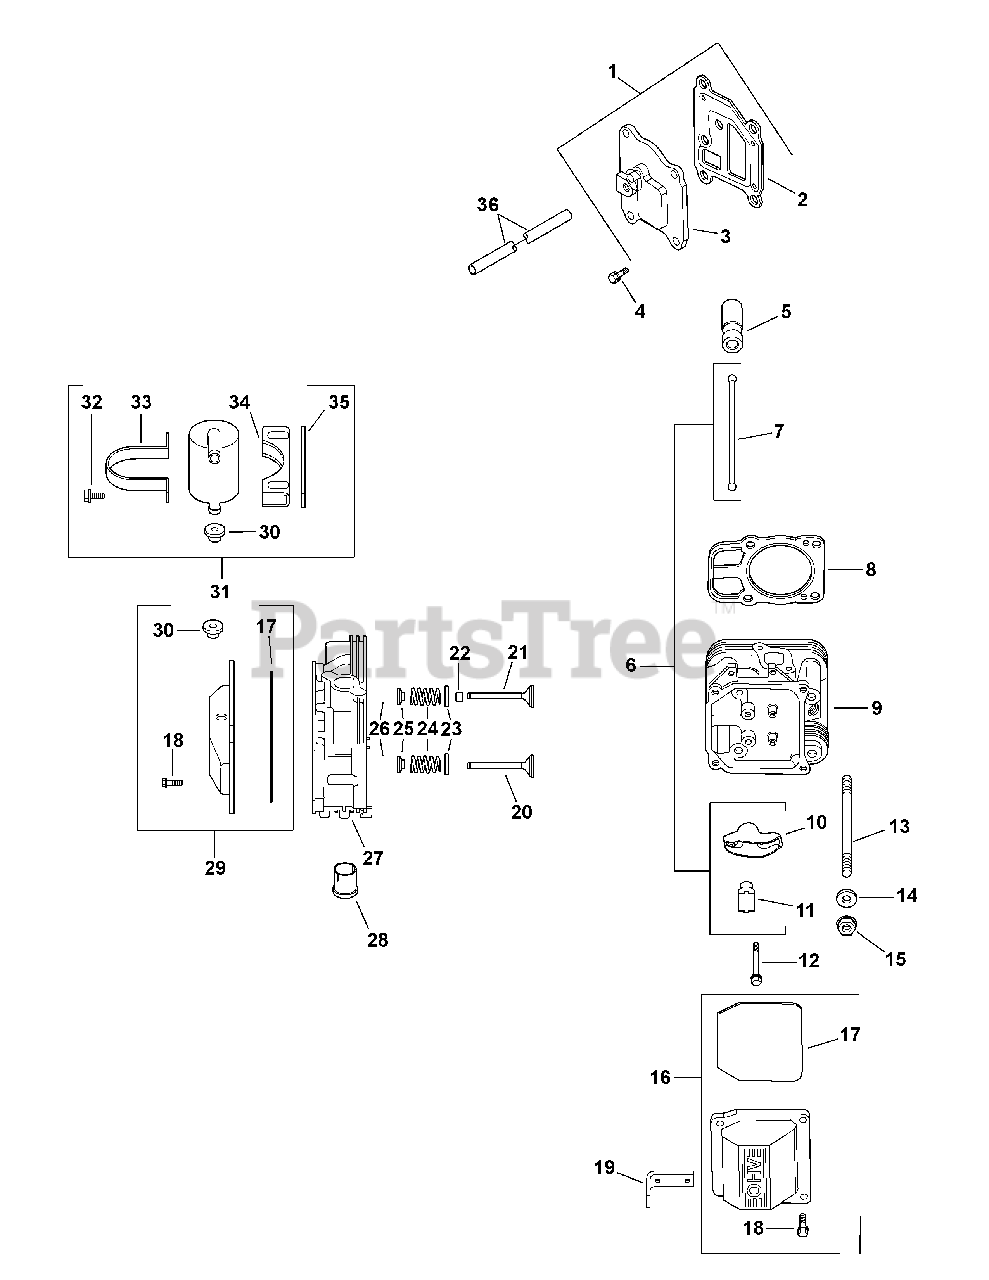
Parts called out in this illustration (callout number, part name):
1	Breather Cover Kit w/ Gskt. (Inc. 2 & 3)
2	Breather Gasket
3	Breather Cover
4	Flange Screw, M6 x 1.0 x 20
5	Hydraulic Valve Lifter Kit
6	Valve Train Kit (Inc. 7, 10 & 11)
8	Cylinder Head Gasket Kit
9	#2 Cylinder Head Assembly Kit
11	Rocker Arm Pivot
12	Flange Screw, M6 x 1.0 x 34
13	Stud, M8 x 1.25
14	Flat Washer, 8.6 mm
15	Flange Nut, M8 x 1.25
16	Plain Rocker Cover Kit (Inc. 17 & 18)
17	Valve Cover O-Ring
18	Flange Screw, M6 x 1.0 x 30
19	Lifting Strap
20	Exhaust Valve (STD)
20	Exhaust Valve (.25)
21	Intake Valve (STD)
21	Intake Valve (.25)
22	Valve Stem Seal
23	Spring Retainer
25	Valve Spring Cap
27	#1 Cylinder Head Assembly Kit
28	Exhaust Port Liner
29	Breather Rocker Cover Kit (Inc. 17,18 & 30)
30	Rubber Grommet
31	Breather Separator Kit (Inc. 30-35)
32	Flange Screw, M6 x 1.0 x 16
33	Breather Strap
34	Breather Separator Bracket
36	Breather Hose
